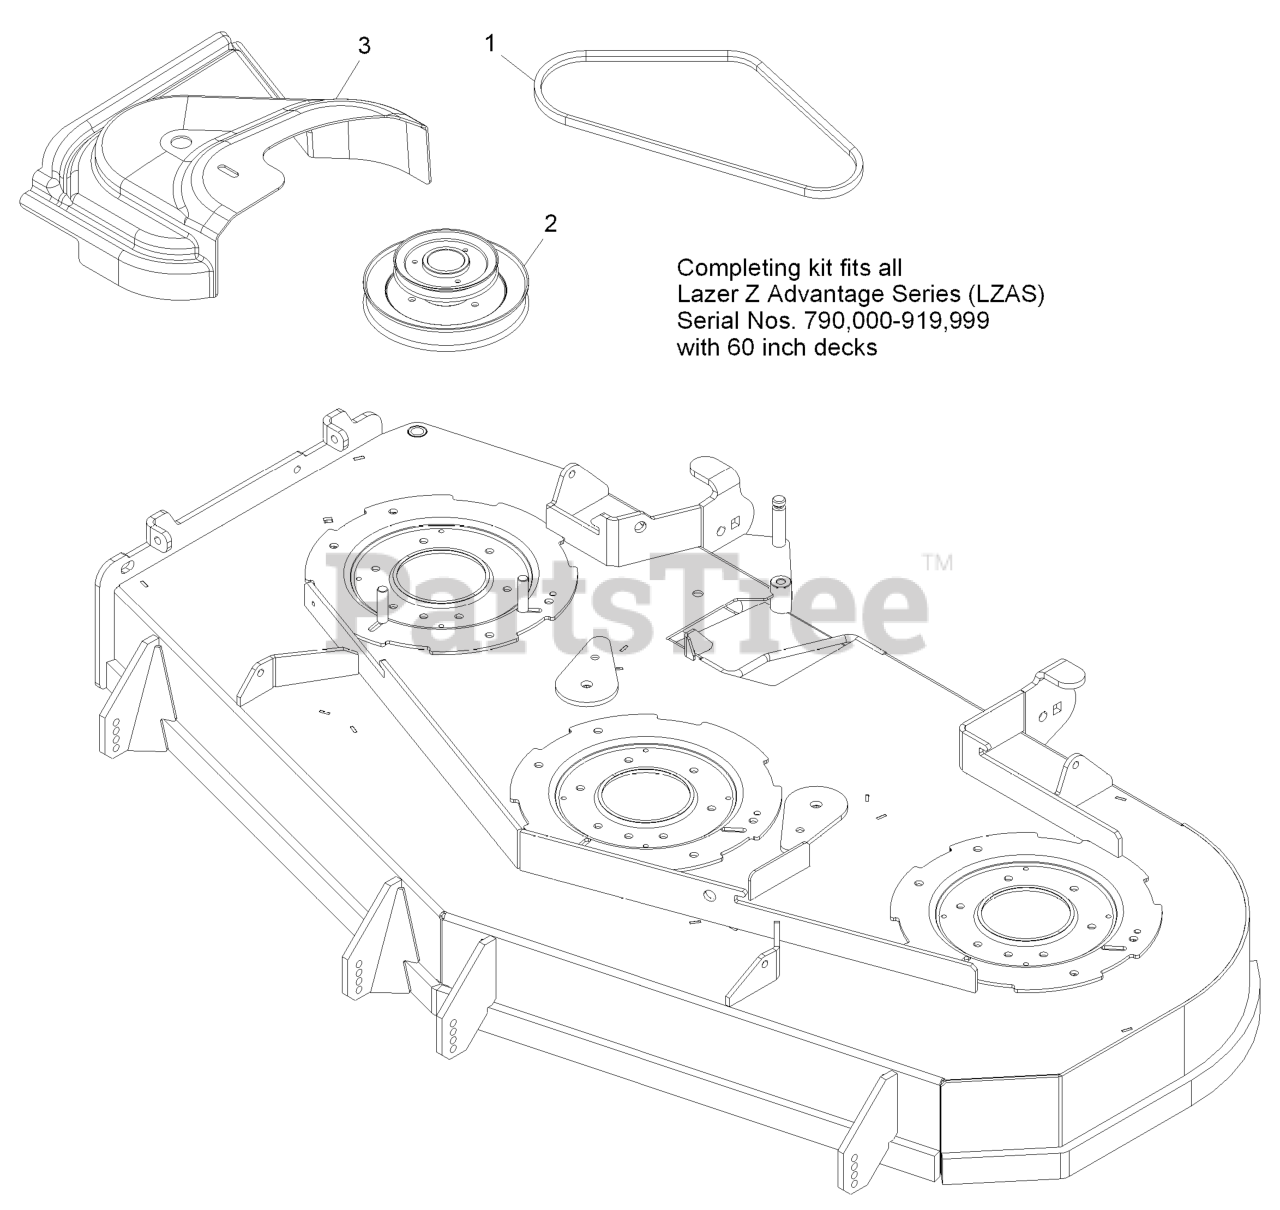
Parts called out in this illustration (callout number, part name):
1	BELT, BLOWER DRIVE 60
2	JACKSHAFT,UV DRIVE 604
3	COVER,BELT UV 60
